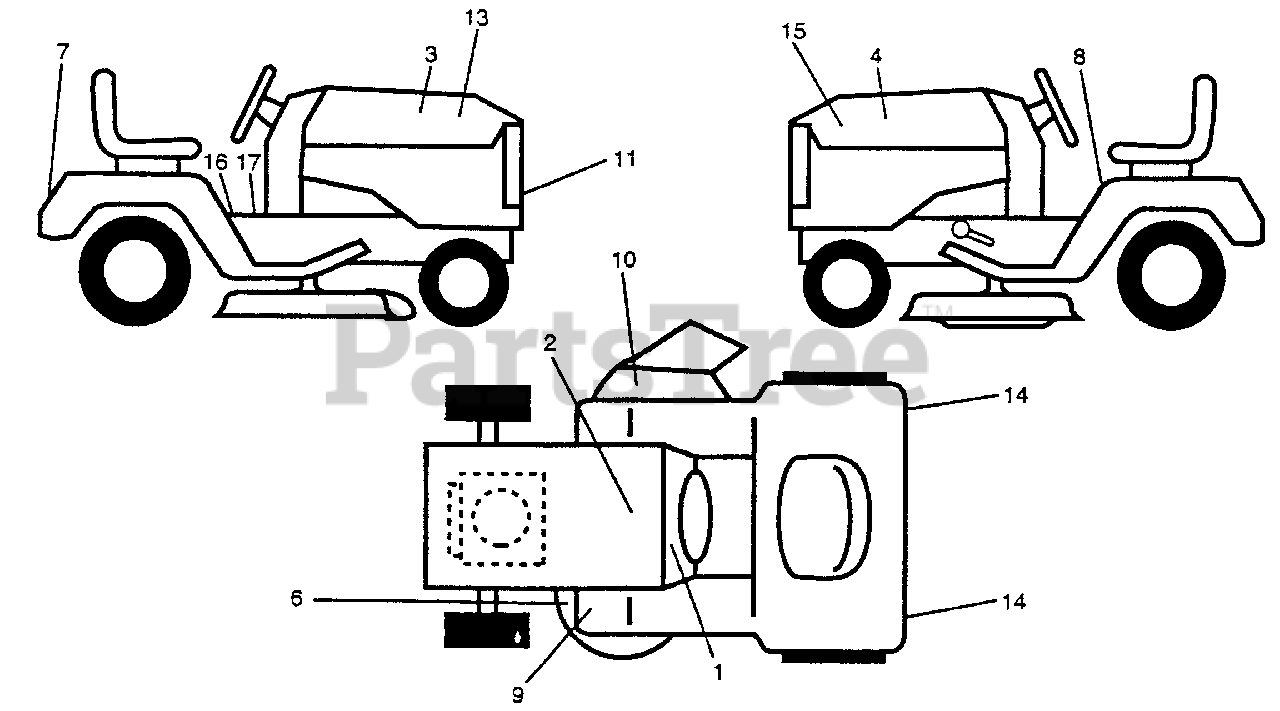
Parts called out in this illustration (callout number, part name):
1	Decal Instruction Dash Eng/fr
2	Decal Bat DAN/POI P/L Symbols
3	Decal Hood RH Husq YT 180 Insert
4	Decal Hood LH Husq YT 180 Insert
6	Decal V-Belt Sch
7	Decal Fender Husqvarna
8	Decal Caution Fender Eng/fr
9	Decal Clutch/brake Eng/fr
10	Decal Warning MULT-LANGUAGE
11	Decal Grille Husqvarna
13	Decal Hood RH Husqvarna
14	Reflector Tail Light Red/amber
15	Decal Hood RH Husqvarna
16	Decal Sdl Cold Start Hyd Eng/Fr
17	Decal Brake Parking Saddle
